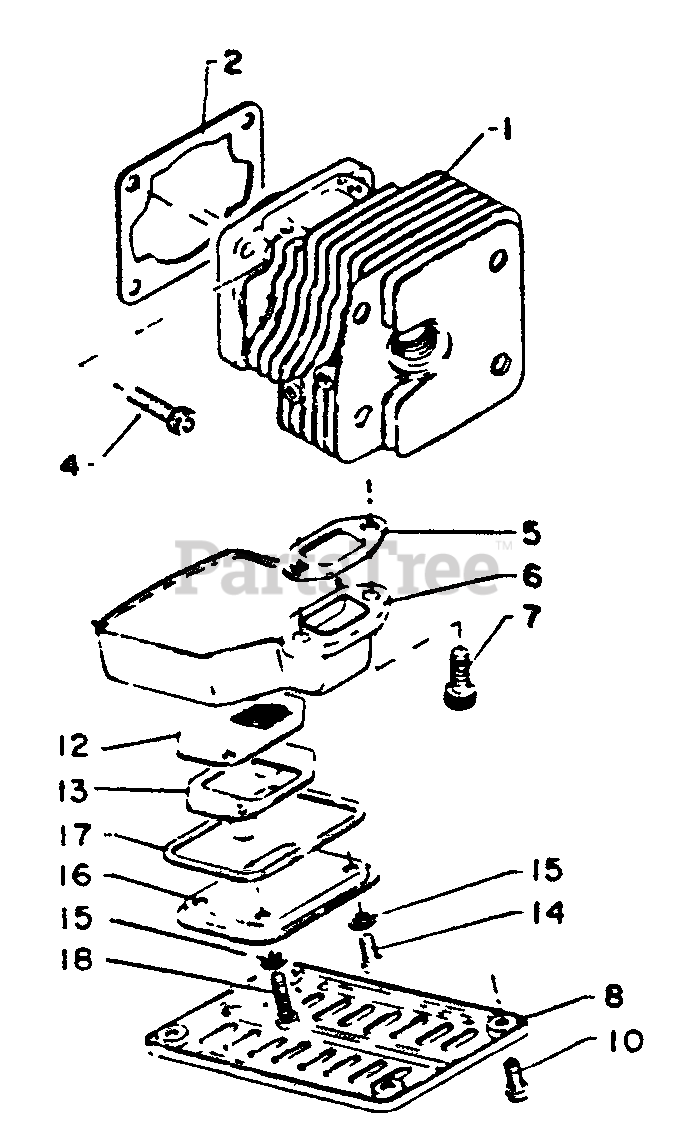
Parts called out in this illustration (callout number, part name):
1	CYLINDER
2	GASKET, CYLINDER
4	SCREW - 5X20
5	GASKET, EXHAUST
6	COVER, MUFFLER
7	SCREW - 5X15
8	COVER, MUFFLER
10	SCREW - 4X10
12	SCREEN, SPARK ARRESTOR
13	RETAINER, SCREEN
14	SCREW - 4X6
15	LOCKWASHER - 4
16	COVER, MUFFLER
17	GASKET, EXHAUST
18	SCREW - 4X14
